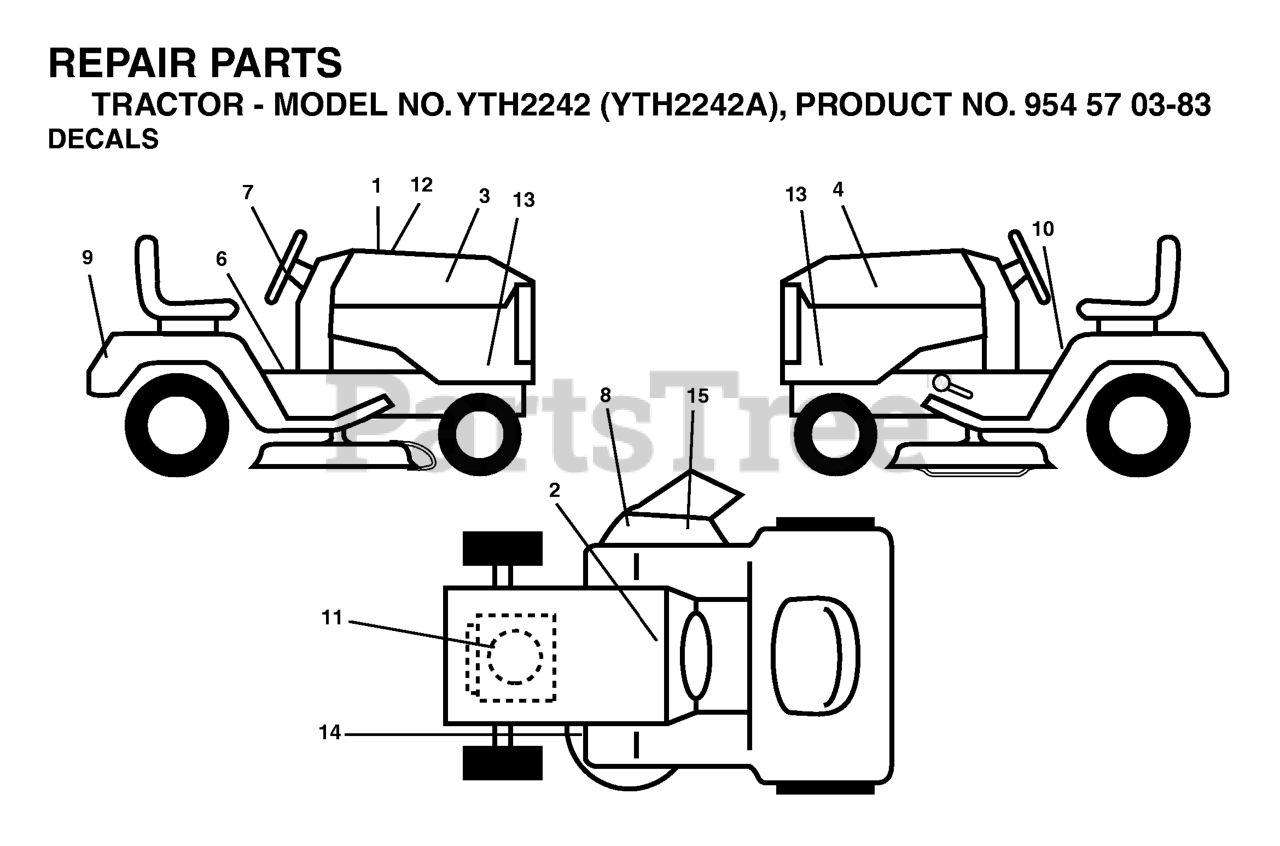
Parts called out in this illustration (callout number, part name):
1	DECAL HOOD CUST. RESP.
2	DECAL BTRY SYMBOLS
3	DECAL.HOOD.RH
4	DECAL.HOOD.LH
7	DECAL.WHEEL.STEERING.HUSQ.PERM
8	DECAL.WARN.KEEP.HAND.AWAY
9	DECAL, FENDER
10	DECAL FENDER DANGER
13	SIDE PANEL DECAL
14	DECAL V BELT SCHEMATIC
15	DECAL DECK "B" 42"
